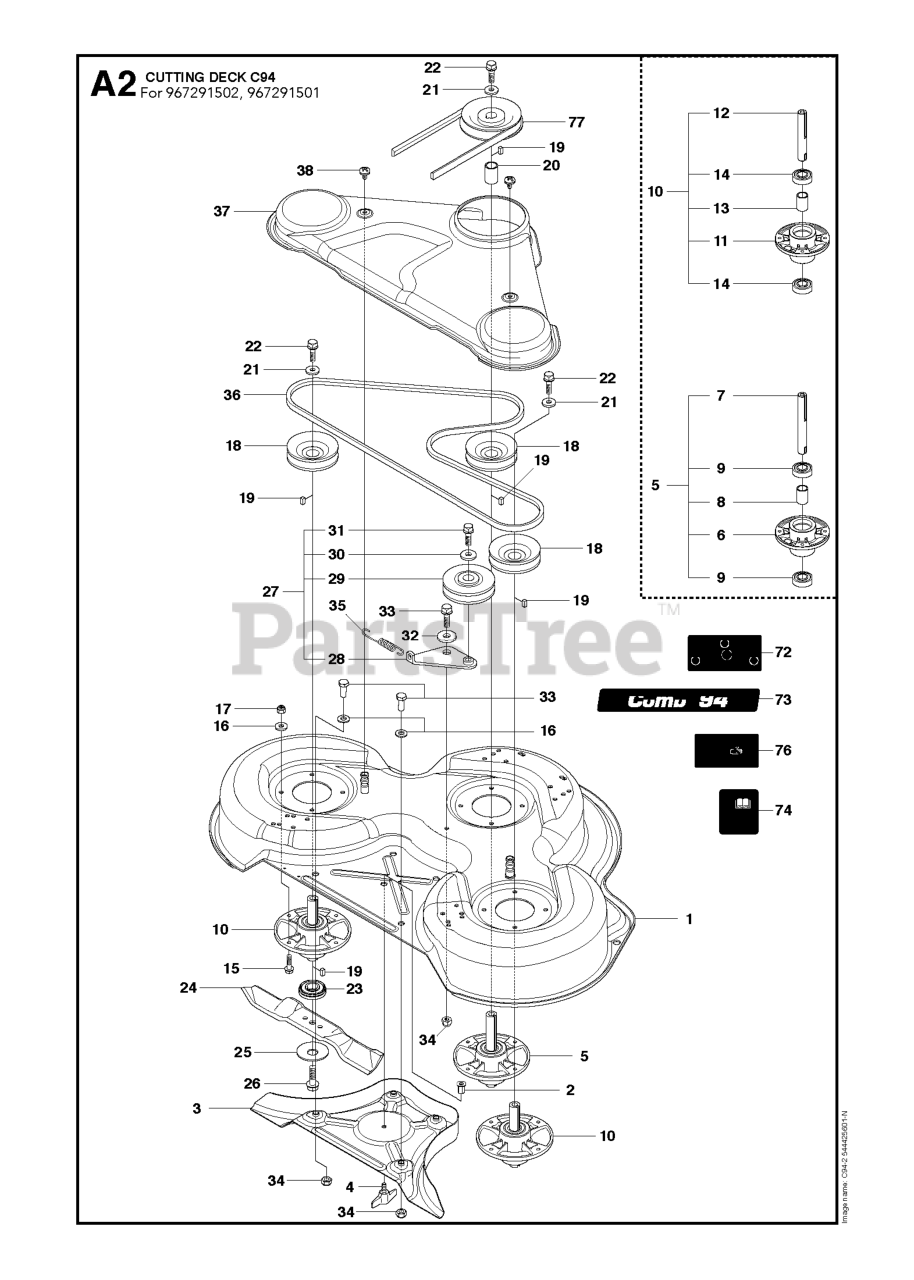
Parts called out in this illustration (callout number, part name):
4	PLUG C93 & C94
6	BLADE HOUSING ASSY
9	SPACING SLEEVE
10	BEARING HOUSING
14	SPACING SLEEVE
15	BEARING HOUSING
17	WASHER BRB 8.4X17
18	LOCKNUT M8
21	SPACING SLEEVE
25	BLADE BRACKET
30	PULLEY
33	WASHER
